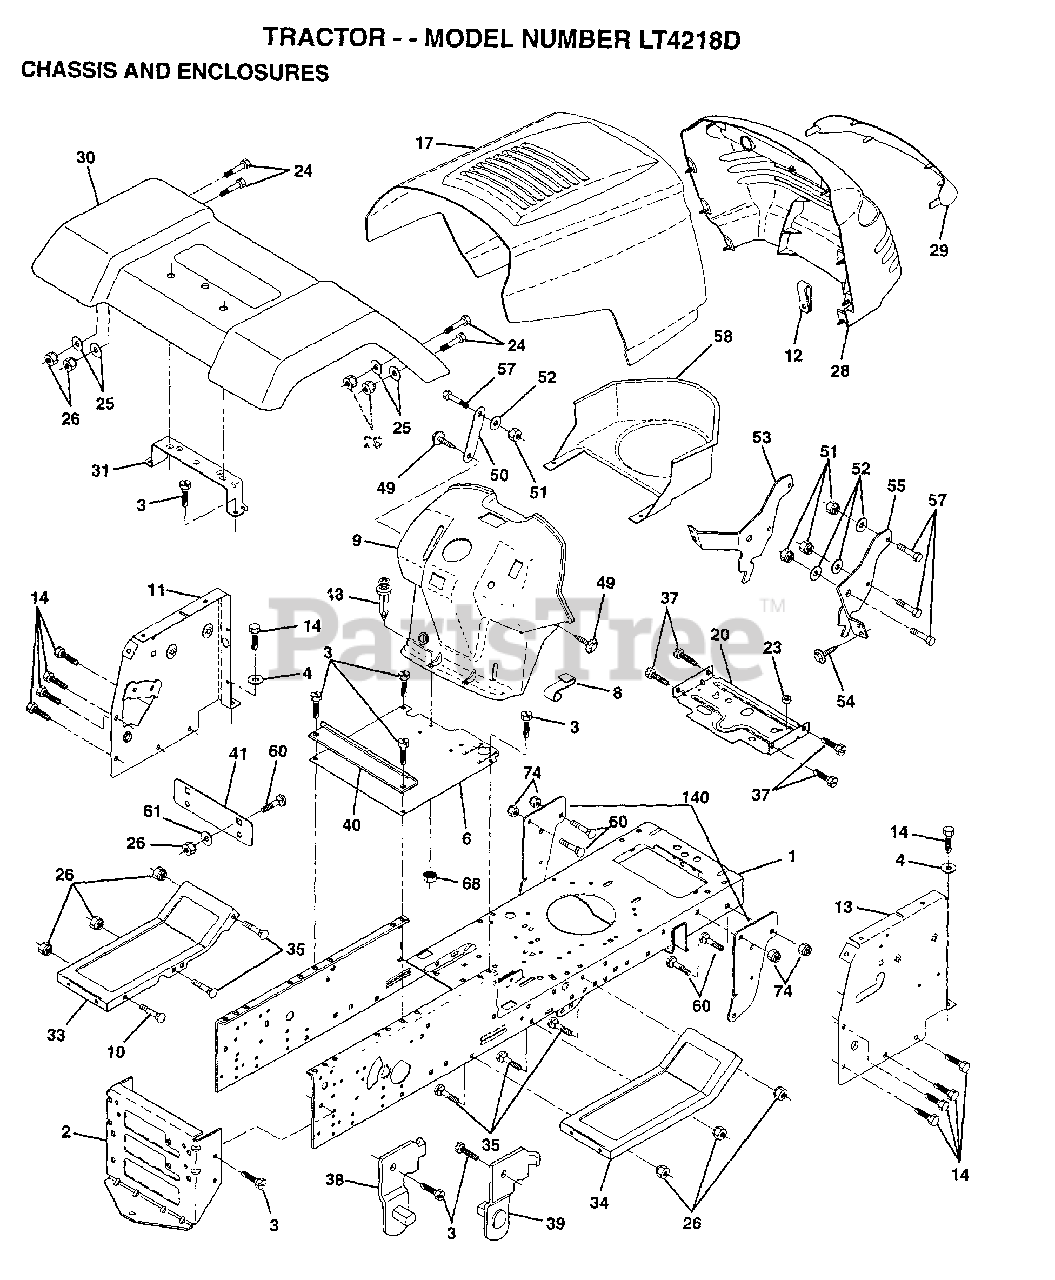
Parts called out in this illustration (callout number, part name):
1	CHASSIS WLDMT 11G
3	SCREW
4	WASHER
8	"CLIP,INSULATOR"
11	PANEL.DASH.LH.
12	CLIP.TINNERMAN
13	PANEL.DASH.RH
14	SCREW LT
20	PLATE.MTG.BTRY.TK
24	BOLT
25	WASHER
26	NUT
28	GRILL QUADRA
29	LENS QUADRA
31	BRACKET SUPT FEND
33	FOOTREST.LH.LT/GT
34	FOOTREST.RH.LT/GT
35	BOLT
37	SCREW LT
38	BRACKET ASM LH
39	BRACKET ASM RH
40	SPACER FENDER LT
41	PLATE EXTEN FEND
48	RIVET.PUSH.PLATE
49	SCREW HEX CRT
50	BRACE SUPT DASH
51	NUT
52	WASHER
53	BRACKET.GRILLE.LH
55	BRACKET.GRILLE.RH
58	DUCT.AIR.B&S.18HP
60	BOLT
61	WASHER
68	NUT
